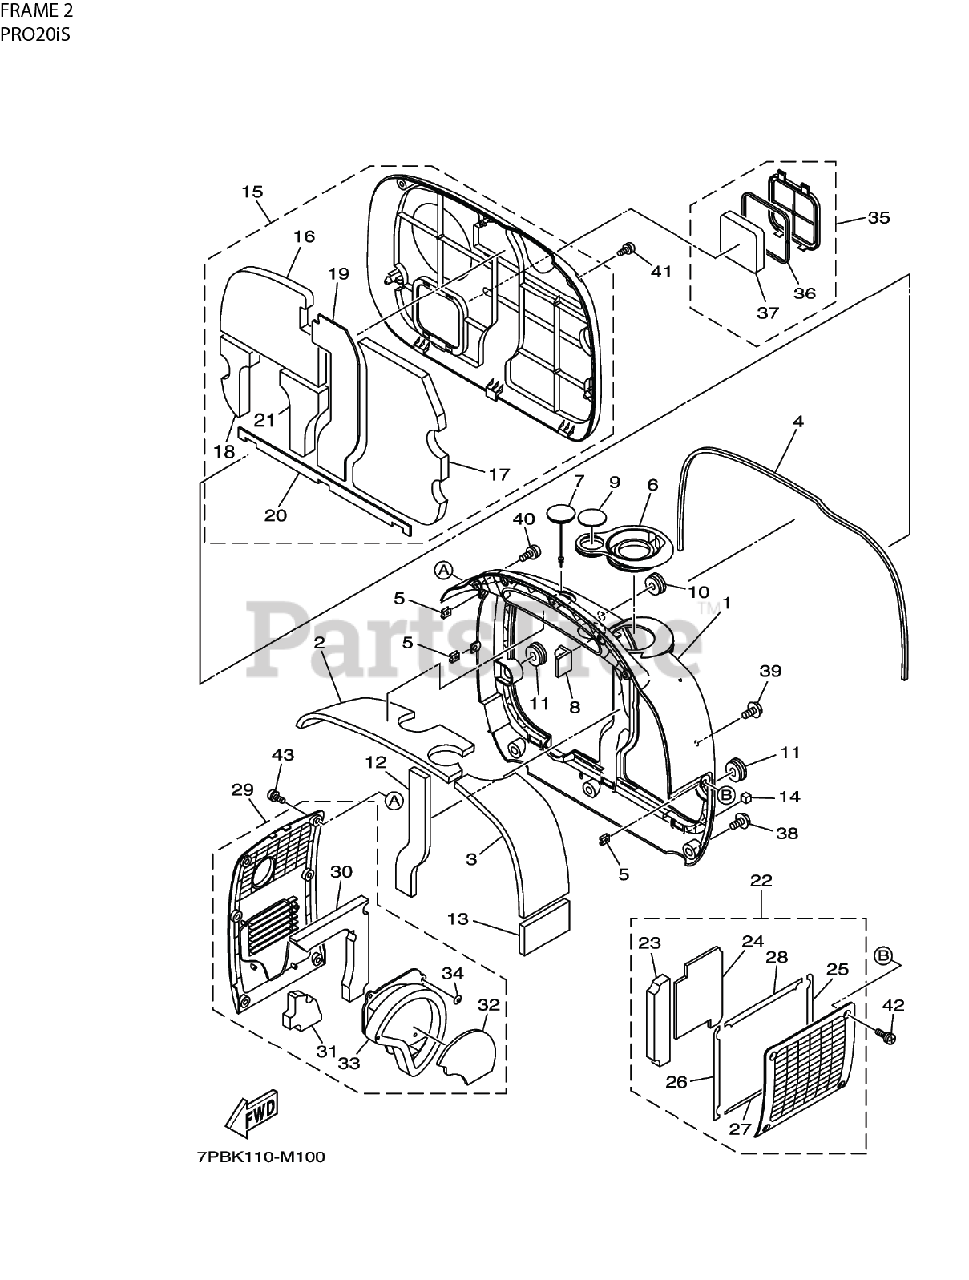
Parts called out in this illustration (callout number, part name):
1	COVER, AIR CLEANER - REAR
4	DAMPER, PLATE
5	NUT, FLANGE
7	PLUG, COVER 2
9	CAP, LENS LEVEL GAUGE
13	DAMPER, PLATE
14	DAMPER, PLATE
15	COVER, AIR CLEANER - COVER ASSY 4
22	COVER, AIR CLEANER - COVER ASSY 5
25	SEAL, RUBBER 7
26	SEAL, RUBBER 8
27	SEAL, RUBBER 9
28	SEAL, RUBBER 10
29	COVER, AIR CLEANER - COVER ASSY 6
34	NUT, SPRING
38	SCREW - BOLT
39	SCREW - BOLT FLANGE
40	SCREW - PAN HEAD
41	SCREW - PAN HEAD
42	SCREW - PAN HEAD
43	SCREW - PAN HEAD
